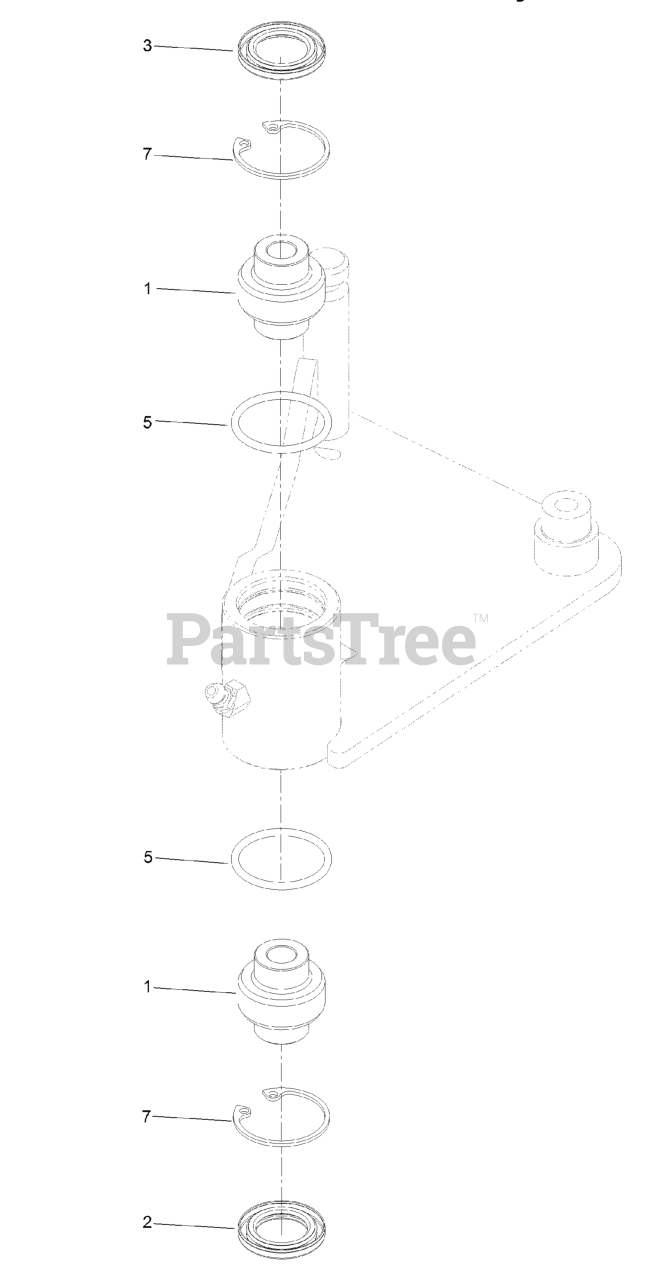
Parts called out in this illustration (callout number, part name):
1	BEARING-SPHERICAL
2	SEAL-LIP, DOUBLE
3	SEAL-LIP, SINGLE
7	RING-SNAP
